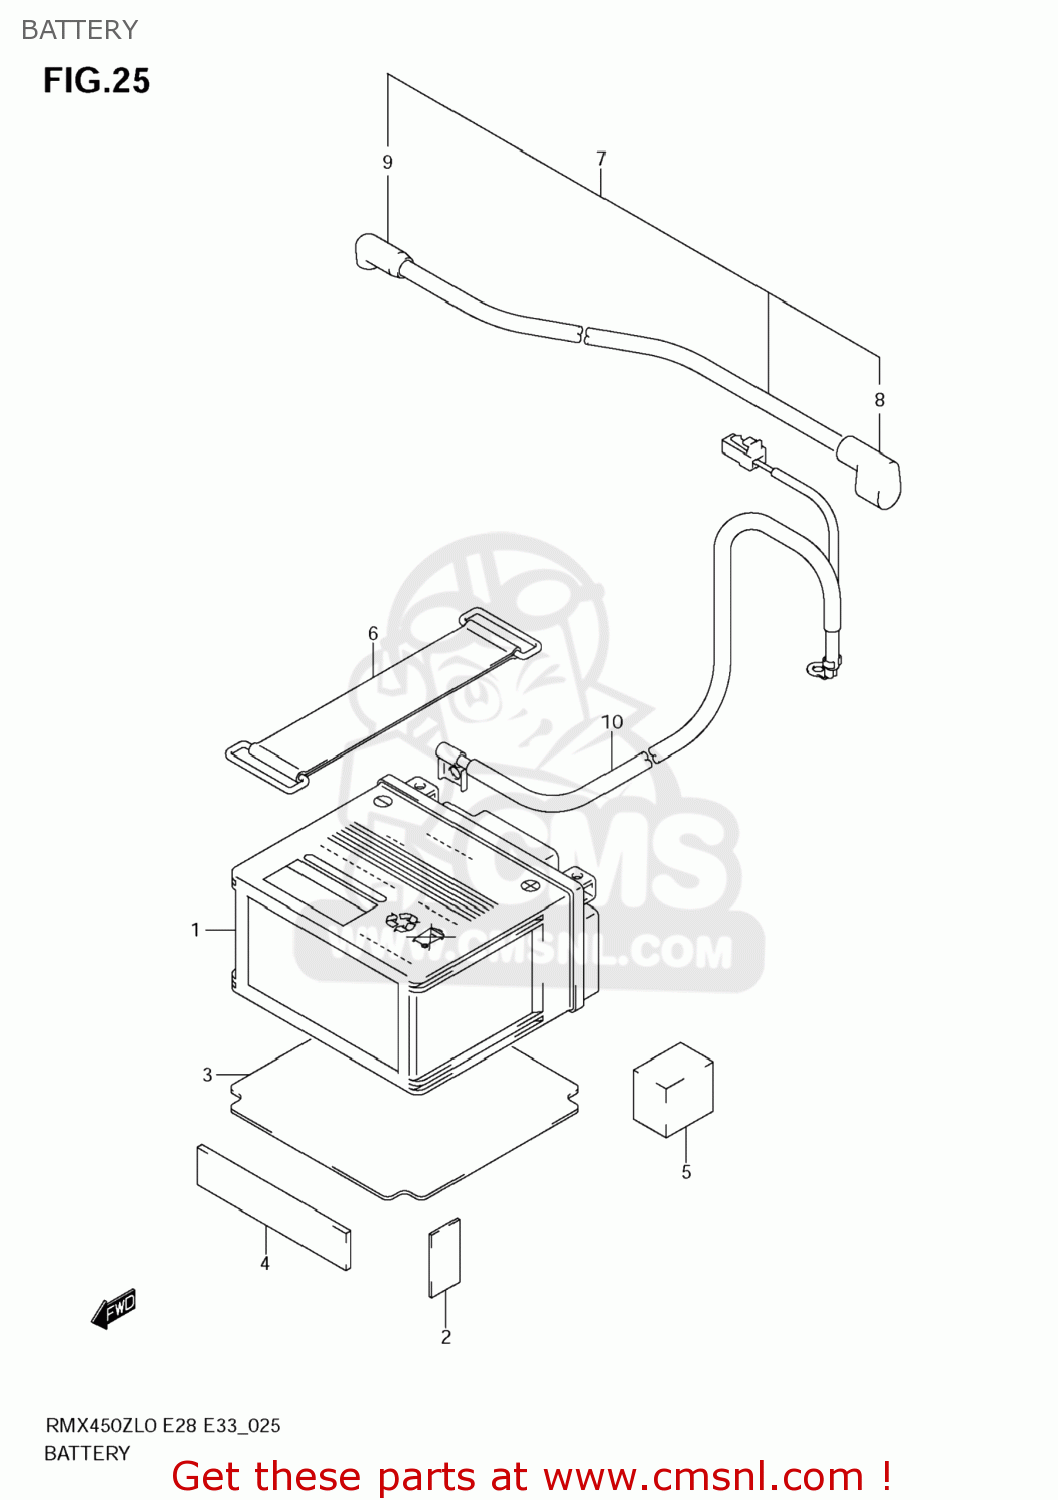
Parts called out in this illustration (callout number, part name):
1	ACCU 12V YTZ7S
2	PROTECTOR,BATTERY
3	PROTECTOR,BATTERY NO.2
4	PROTECTOR,BATTERY
5	PROTECTOR,BATTERY
6	BAND
7	WIRE,STARTER MOTOR LEAD
8	CAP,STARTER RELAY
9	CAP,STARTER MOTOR
10	WIRE,BATTERY MINUS LEAD
